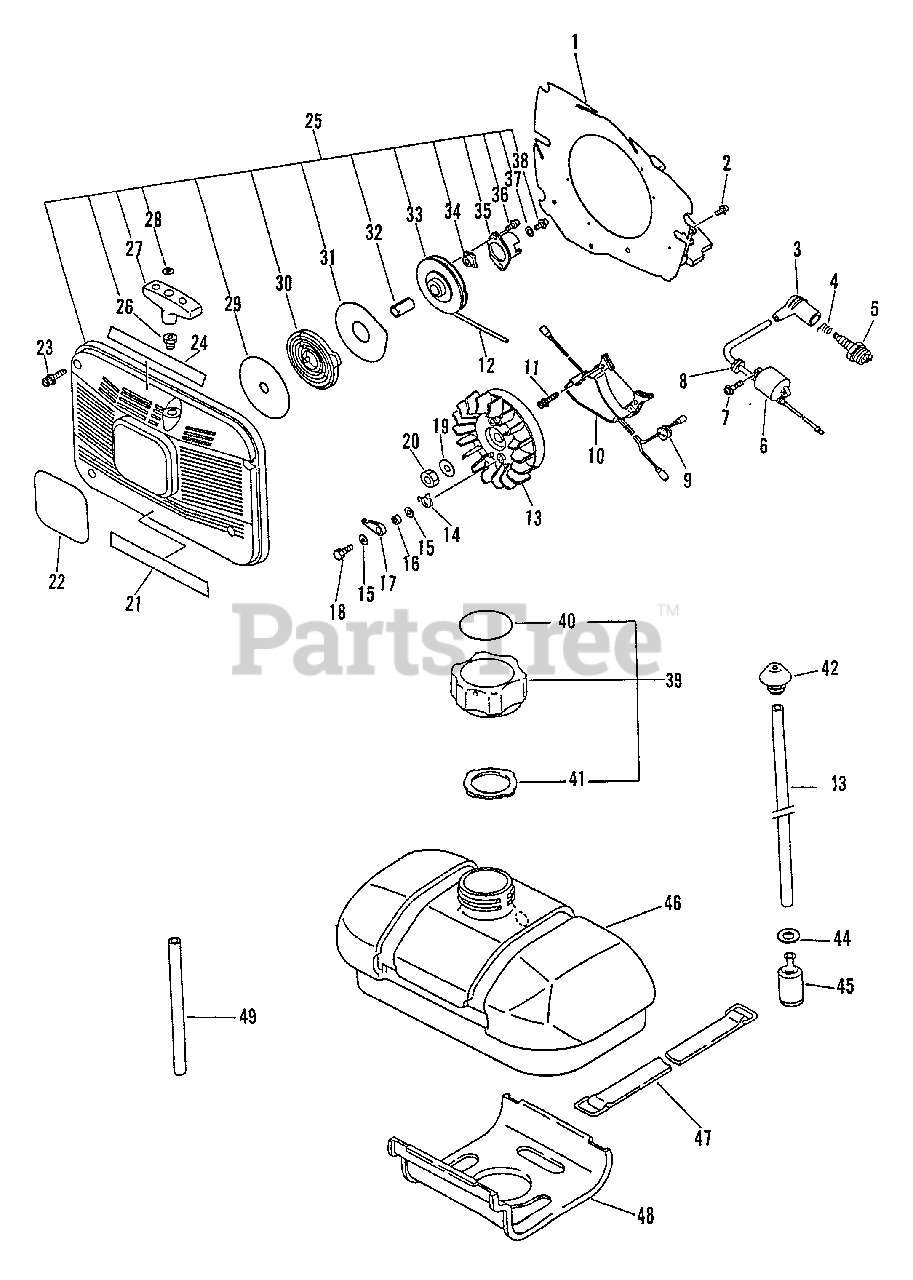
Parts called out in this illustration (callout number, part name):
1	PLATE
2	SCREW 4×12
3	CAP, SPARK PLUG
4	TERMINAL, SPARK PLUG
5	SPARK PLUG - BPM7A
6	COIL, IGNITION
7	SCREW 4×14
10	COIL, IGNITION
11	SCREW - 4×18
12	ROPE, STARTER 4.0×950
13	FLYWHEEL
15	WASHER 5.5×12×0.8
17	PAWL, STARTER
18	BOLT - 5×16
19	WASHER - 10
20	NUT - 10
21	LABEL, CAUTION
22	LABEL, REC-600
23	SCREW 5×20
24	LABEL, CAUTION
25	STARTER ASSY
26	GUIDE, ROPE
29	PLATE, STARTER
30	SPRING, RECOIL
31	PLATE, SIDE
33	REEL, ROPE
34	RETAINER, ROPE
35	PAWL CATCHER
36	SCREW 4×10
37	WASHER 5.2×16×1.0
38	SCREW 5×10
39	CAP ASSY
40	LABEL - FUEL MIX
41	GASKET, CAP
43	PIPE - 3×6×220
44	WASHER 5.5×12×0.8
45	FILTER, FUEL
46	TANK, FUEL
47	BAND, FUEL TANK
48	CUSHION
49	PIPE, FUEL 3×6×150
